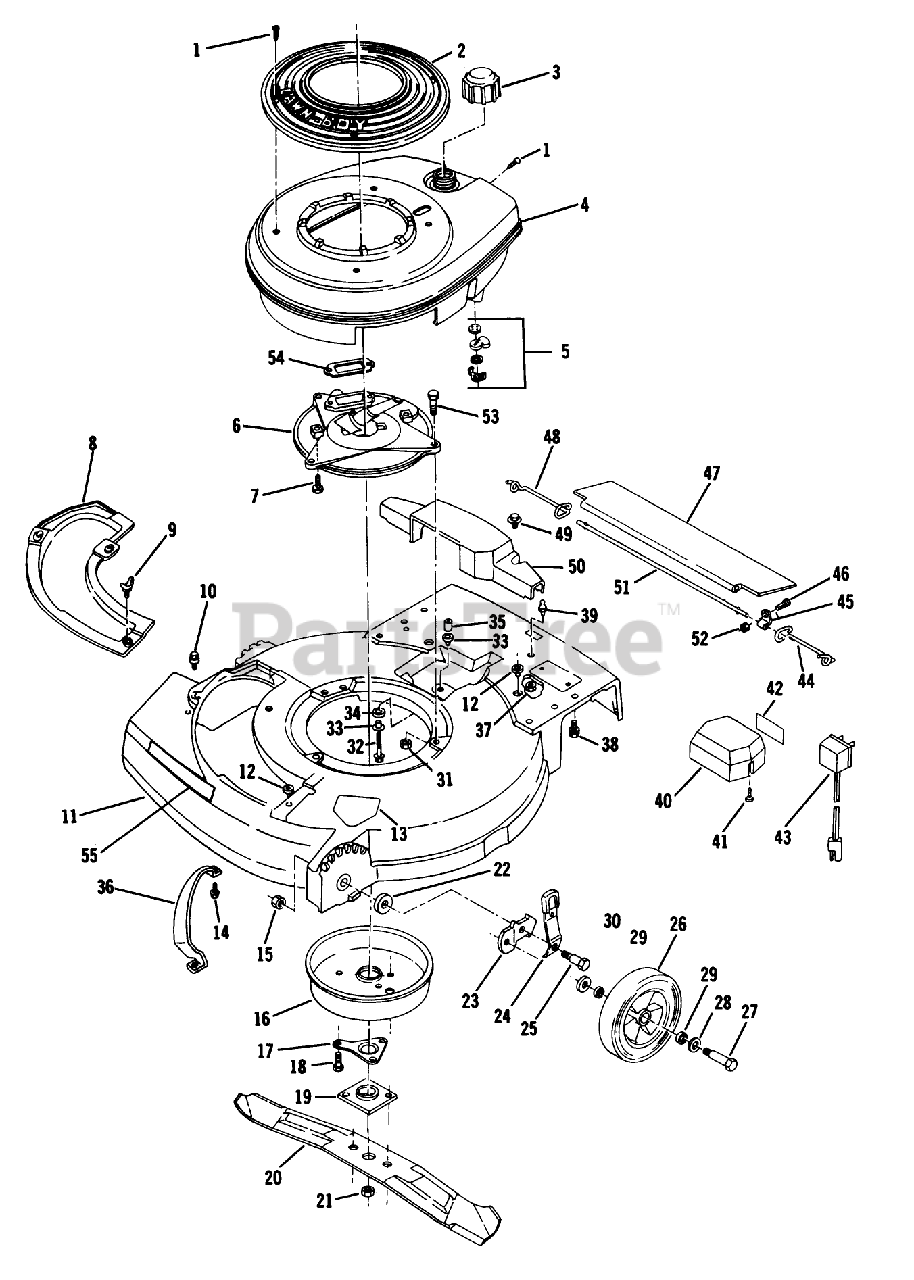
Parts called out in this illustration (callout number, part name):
1	SCREW - SELF TAPPING
3	FUEL CAP & INSERT
5	SHUT OFF VALVE KIT
7	SCREW V
9	WING SCREW LAWRE
15	LOCKNUT
16	MUFFLER COVER F
17	SUPPORT F
18	SCREW
19	PLATE AND COLLAR ASM
21	NUT-BLADE
22	WASHER
25	BOLT
26	WHEEL & TIRE KIT
27	BOLT WHEEL
28	SPACER
29	WASHER
30	WASHER WROUGHT
31	NUT-LOCK F
33	SPACER ECK PRES
34	GROMMET
35	SPACER
36	BAR-TOE
38	SCREW
44	SPRIG T/SHLD ASOC
45	CLAMP ROD KMC
47	SHIELD
48	SPRING;TRAILING SHIELD RH
49	SCREW SEMS TRM HEX HD
51	ROD 21" ADVANCE
52	LOCKNUT E
53	SCREW-HH
